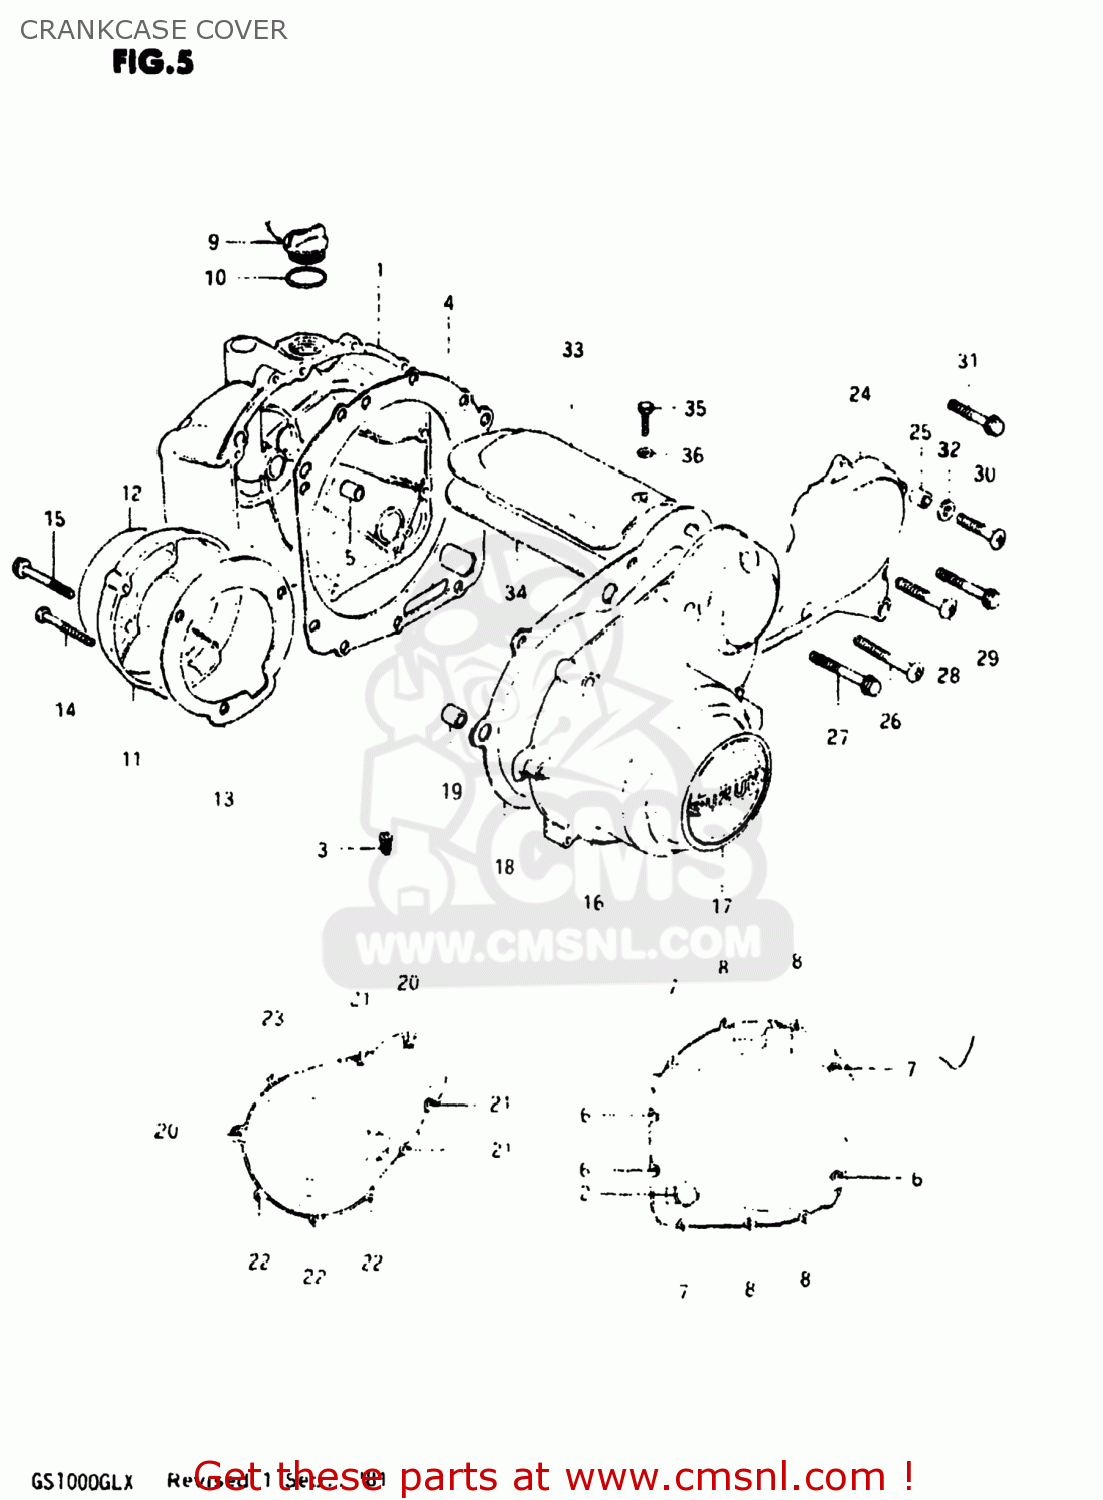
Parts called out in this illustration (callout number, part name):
1	COVER,CLUTCH
2	LENS,OIL LEVEL CHECK
3	JET
4	GASKET,MAGNETO COVER (N (MCA)
5	PIN
6	BOLT (6X35)
7	SCREW 6X30
8	BOLT
9	CAP
10	O RING(D:2.2,ID:32)
11	COVER,CONTACT BREAKER
12	EMBLEM,CONTACT BREAKER COVER
13	GASKET,CONTACT BREAKER COVER (NAS)
14	SCREW
15	BOLT (5*30)
16	COVER
17	EMBLEM,MAGNETO COVER
18	GASKET,MAGNETO COVER (MCA)
19	PIN
20	BOLT
21	SCREW
22	BOLT (6X35)
23	SCREW 6X30
24	COVER,SPROCKET
25	PIN
26	SCREW 6X30
27	BOLT (6X30)
28	SCREW
29	BOLT
30	SCREW
31	BOLT (6X20)
32	WASHER
33	COVER,STARTER MOTOR
34	GASKET,STARTER MOTOR COVER (MCA)
35	BOLT
36	WASHER
